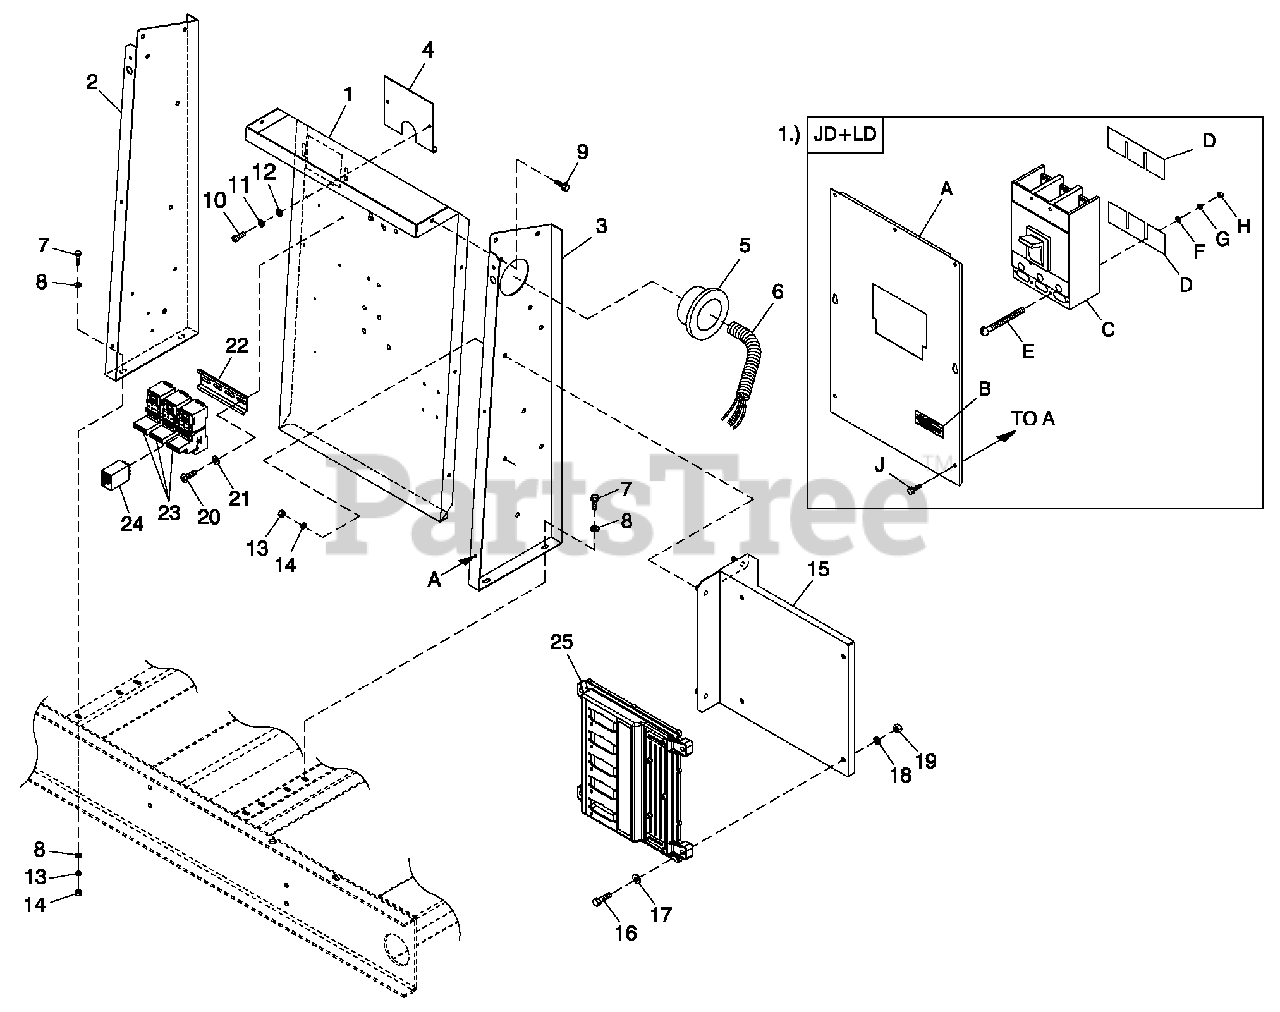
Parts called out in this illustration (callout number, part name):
1	PANEL CB CONN BOX
1	UL CIRCUIT BREAKER (JD+LD)
2	STAND LH CONTROL C5 GRBX
3	STAND RH CONTROL C5
4	PLATE WIRE SNGLGALV
5	BUSHING SNAP SB-2.5-31
6	CONDUIT FLEX 2.0" ID
7	SCREW HHTT $6-1.0 X 16 ZYC
8	WASHER FLAT 1/4-M6 ZINC
9	SCREW THF M6-1 X 16 N WA Z/JS
10	SCREW PHTT M5-0.8 X 16 ZYC
11	WASHER LOCK M5
12	WASHER FLAT M5
13	WASHER LOCK M6-1/4
14	NUT HEX M6X 1.0 G8YEL CHR
15	MOUNT POWER MANAGER CPL
16	SCREW HHCM8-1.25X 30 G8.8
17	WASHER FLAT 5/16-M8 ZINC
18	WASHER LOCK M8ZINC
19	NUT HEX M8-1.25 G8 CLEAR ZINC
20	SCREW PHTT M4-0.7 X 10 ZYC
21	WASHER LOCK #8-M4
22	RAIL TERMINAL BLOCK 98MM
23	BASE RELAY DIN MOUNT 4PDT14P
24	RELAY 4PDT12VDC COIL 5A 250V
25	ASSY PROGRAMMED PMGC
A	COVER CIR BRKR JD/LD
B	DECAL DANGER HIGH VOLTAGE
C	CB 0600A 3P 600V S LD6 1A
D	INSULATOR CIRCUIT BR. JD/LD
E	SCREW RHM 1/4-20X3
F	WASHER FLAT 1/4-M6 ZINC
G	WASHER LOCK M6-1/4
H	NUT HEX 1/4-20 STEEL
J	SCREW THF M6-1 X 16 N WA Z/JS
